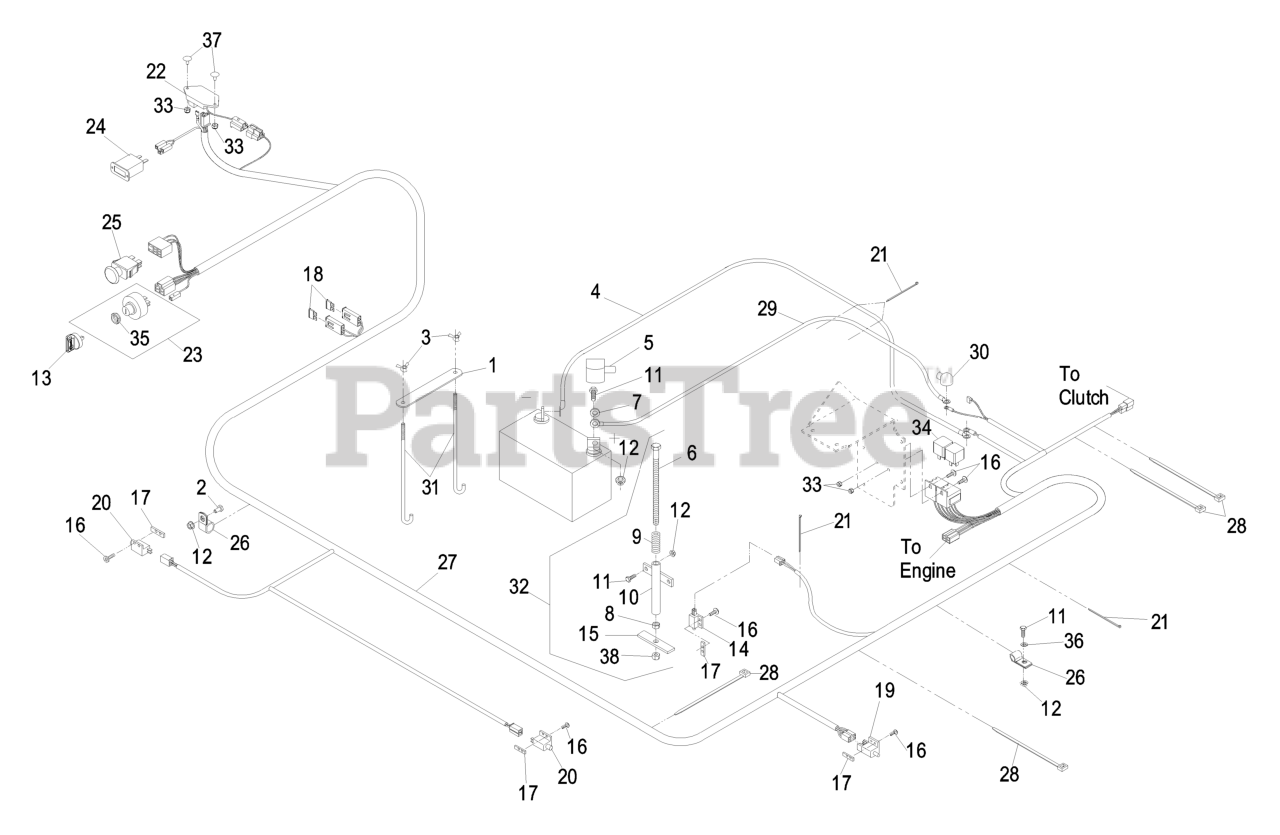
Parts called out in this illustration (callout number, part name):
1	STRAP-HOLDDOWN, BATTERY
2	SCREW-HH
3	WINGNUT
4	WIRE-GROUND
6	SCREW-HH
7	WASHER-FLAT
8	NUT-HEX
9	SPRING-SWITCH, SEAT
10	MOUNT-SPRING, SEAT
11	SCREW-HH
13	KEY-IGNITION
14	SWITCH-CLOSED, NORMALLY
15	PLATE-SWITCH, SEAT
16	SCREW-PPH
17	PLATE-TAPPED
18	FUSE-BLADE TYPE, 20 AMP
20	SWITCH-OPEN, NORMALLY
21	TIE-CABLE
22	MODULE-DELAY, SEAT
23	ASM,SWITCH W/NUT
24	METER-HOUR
25	SWITCH-PTO
26	CLIP-LOOM
27	HARNESS, WIRE LAZER KC
28	TIE-PLASTIC
30	INSULATOR-SOLENOID
31	BOLT-HOLDDOWN
32	ASM,SEAT SWITCH ACTUATOR
33	NUT-LOCK, NI
35	NUT-SWITCH, IGNITION
36	WASHER-FLAT
37	BOLT-CARR
38	NUT-LOCK, NI
